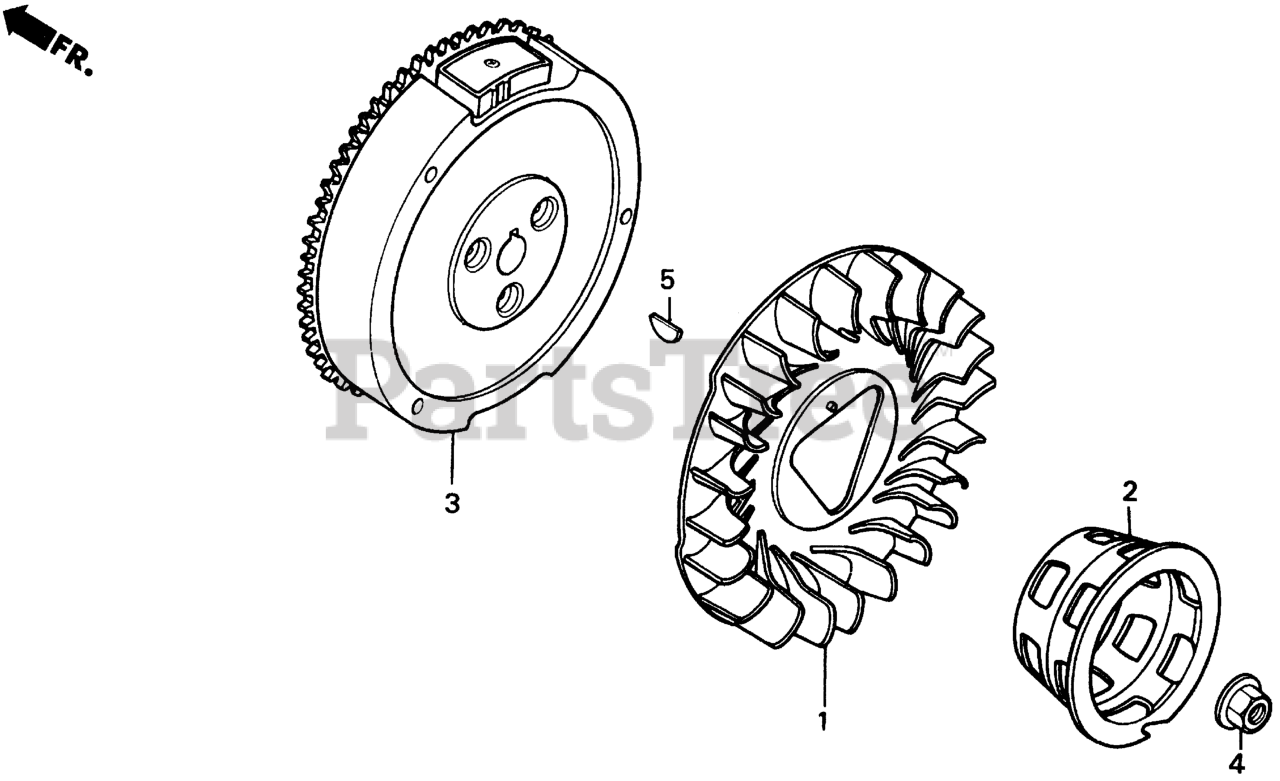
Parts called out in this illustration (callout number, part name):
1	FAN, COOLING
2	PULLEY, STARTER
3	FLYWHEEL (STARTER MOTOR)
4	NUT, SPECIAL (16MM)
5	KEY, SPECIAL WOODRUFF (25X18)
